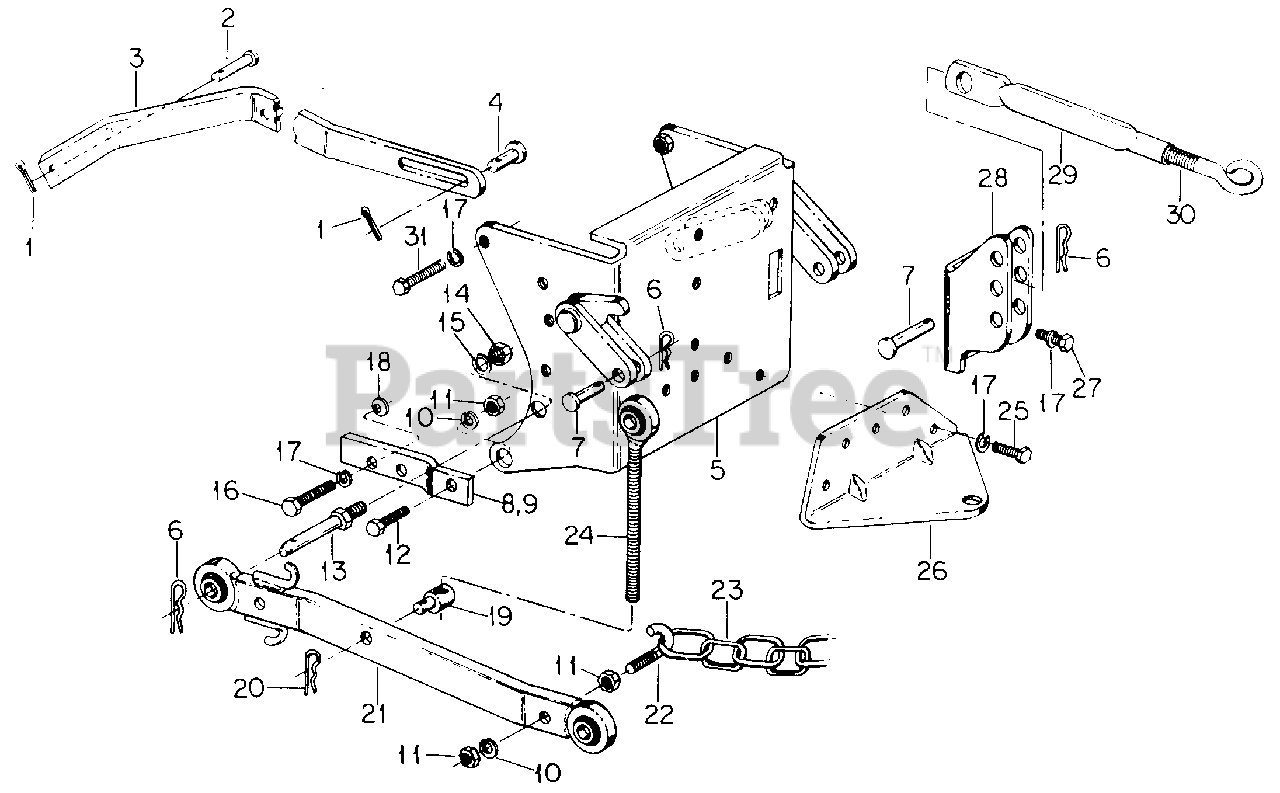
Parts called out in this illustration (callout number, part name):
1	Pin, 1/8 X 1 Cot
2	Pin, 1/2 X 2.562 Pln Clevis
3	Bar, Lift
4	Pin, Clevis
5	Plate Assy, Three Point Hitch
7	Pin, 5/8 X 2.000 Pln Clevis
11	Nut, 7/16 Cad P/T Lock Type 5
12	Bolt, 7/16 X 1 Type 5
13	Link, Clevis Pin
14	Nut, 5/8 Cad P/T Lock Type 5
15	Washer, 5/8 Lock
16	Bolt, 3/8 X 2-1/2 Type 5
17	Washer, 3/8 Lock
18	Washer, Belleville, 3/8 ID
19	Ferrule, Adjustment
21	Bar Assy, Draft
22	Hook, Hitch Chain
23	Chain, Limiter
24	Link Assy, Adjustable Lift
25	Bolt, 3/8 X 1 Type 5
27	Bolt, 3/8 X 7/8 Type 5
30	Screw, Clevis
31	Bolt, 3/8 X 3/4 Type 5
